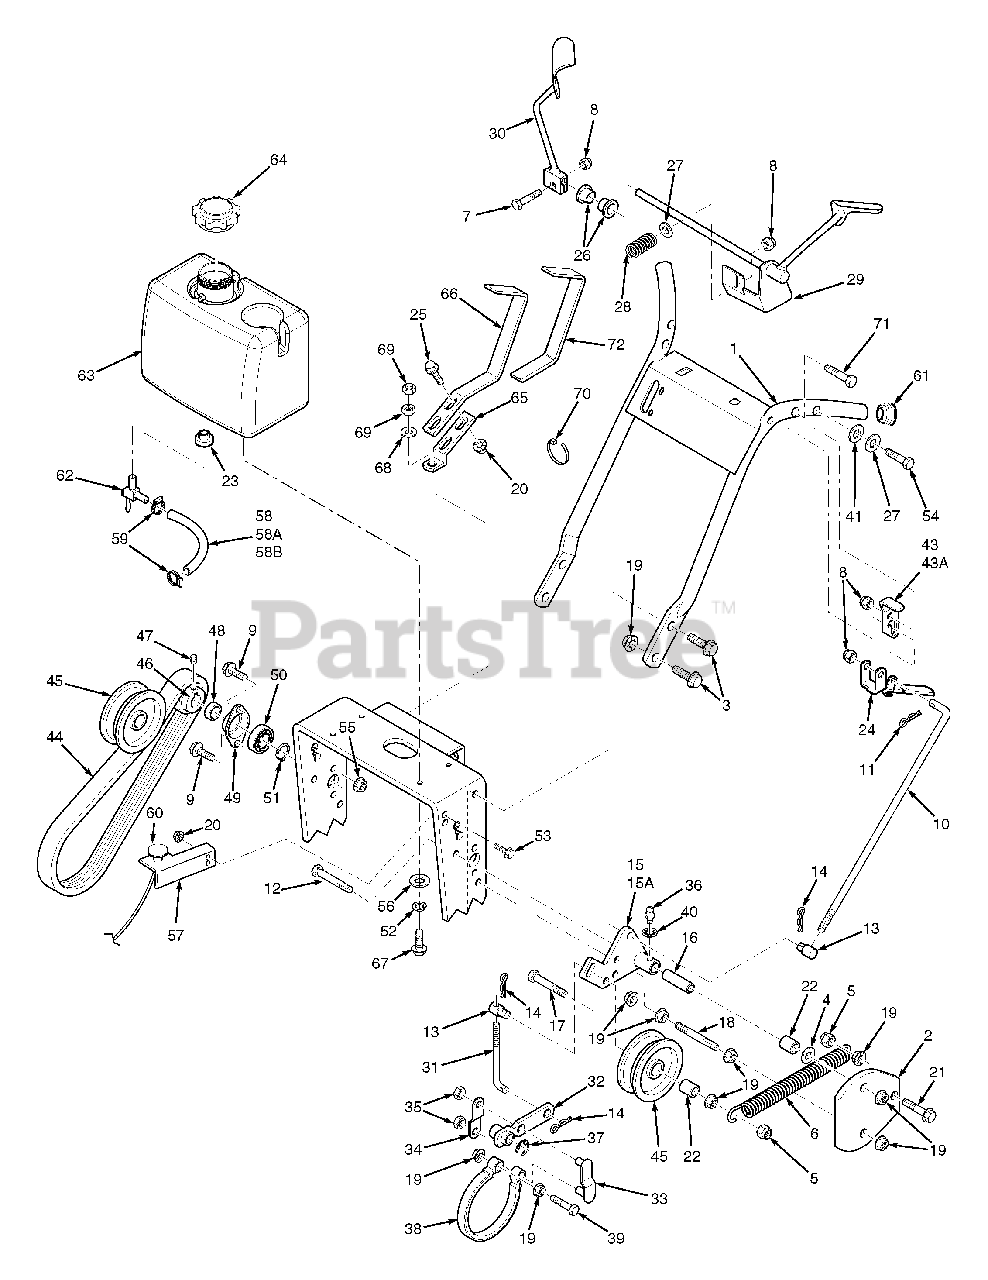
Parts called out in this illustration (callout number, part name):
1	Handle Assembly
2	Belt Guard
3	Capscrw, 3/8-16 x 1" Serr. Flg.
4	Washer, 3/8" (.391 x .938 x .105)
5	Nut, 3/8-16 Elastic Stop
6	Spring, Idler
7	Bolt, 5/16-18 x 1-1/4" Hex Head
8	Nut, 5/16-18 Elastic Stop
9	Capscrew, 1/4-20 x 3/4" Hex Head
10	Control Rod, Steering
11	Hair Pin, Small
12	Bolt, 3/8-16 x 4-1/2" Hex Head
13	Swivel Joint
14	Hair Pin, Large .094 Diameter
15	Idler Bracket, RH
15A	Idler Bracket, LH
16	Idler Sleeve
17	Bolt, 3/8-16 x 3/4" Hex Head
18	Support Belt Guard
19	Nut, 3/8-16 Serrated Flange
20	Nut, 5/16-18 Serrated Flange
21	Cpscrw, 3/16-18 x 1-1/4" Serr. Flg.
22	Spacer
23	Bushing
24	Steering Lever
25	Capscrew, 5/16-18 x 1" Serr. Flg.
26	Bushing
27	Washer, 5/16 (.375 x .875 x .083)
28	Spring, Operator Presence
29	Operator Presence Lever, LH
30	Operator Presence Lever, RH
31	Brake Rod
32	Brake Lever
33	Brake Link
34	Brake Link Plate
35	Nut, 3/8 Push-on
36	Grease Fitting, Straight 1/4-28
37	Retaining Ring, 5/8 Ext. "E"
38	Brake Band
39	Bolt, 3/8-16 x 2" Hex Head
40	1/4" Internal Tooth Lockwasher
41	Curved Spring Washer
42	Socket Head Capscrew #8-32 x 1/2"
43	Neutral Latch, RH
43A	Neutral Latch, LH
44	Belt, Wheel Drive
45	Idler Pulley, Wheel Drive
46	Pulley, Jackshaft
47	Setscrew, Hex Socket Knurl Cup Pt. 5/16-18 (nylock)
48	Spacer, Jackshaft Pulley
49	Flange, Jackshaft Bearing
50	Bearing, Jackshaft
51	Retaining Ring, 5/8 Ext. Basic
52	Lock Washer 5/16"
53	Capscrew, 5/16-18 x 3/4" Serr. Flg.
54	Bolt, 5/16-18 x 2" Hex Head
55	Nut, 1/4-20 Serrated Flange
56	Flatwasher, 5/16 (.375 x .875 x .083)
57	Bracket, Choke Mt.
58	Fuel Hose,1/4"ID, 10" (KH Only)
58A	Fuel Hose,1/4"ID, 23" (KA Only)
58B	Fuel Hose,1/4"ID, 26" (Honda Only)
59	Clamp, Fuel Hose
60	Choke Control
61	Plug, Handlebar
62	Valve, Fuel Shut Off
63	Fuel Tank Assy.
64	Fuel Tank Cap
65	Shift Lever
66	Shift Lever Extention
67	Capscrew, 5/16-18 x 1" Hex Head
68	Washer, 3/8 (.391x .938 x .105)
69	Nut, 3/8-24 UNF
70	Cable Tie
71	Bolt, 5/16-18 x 2-1/2"
72	Grip, Shift Handle
